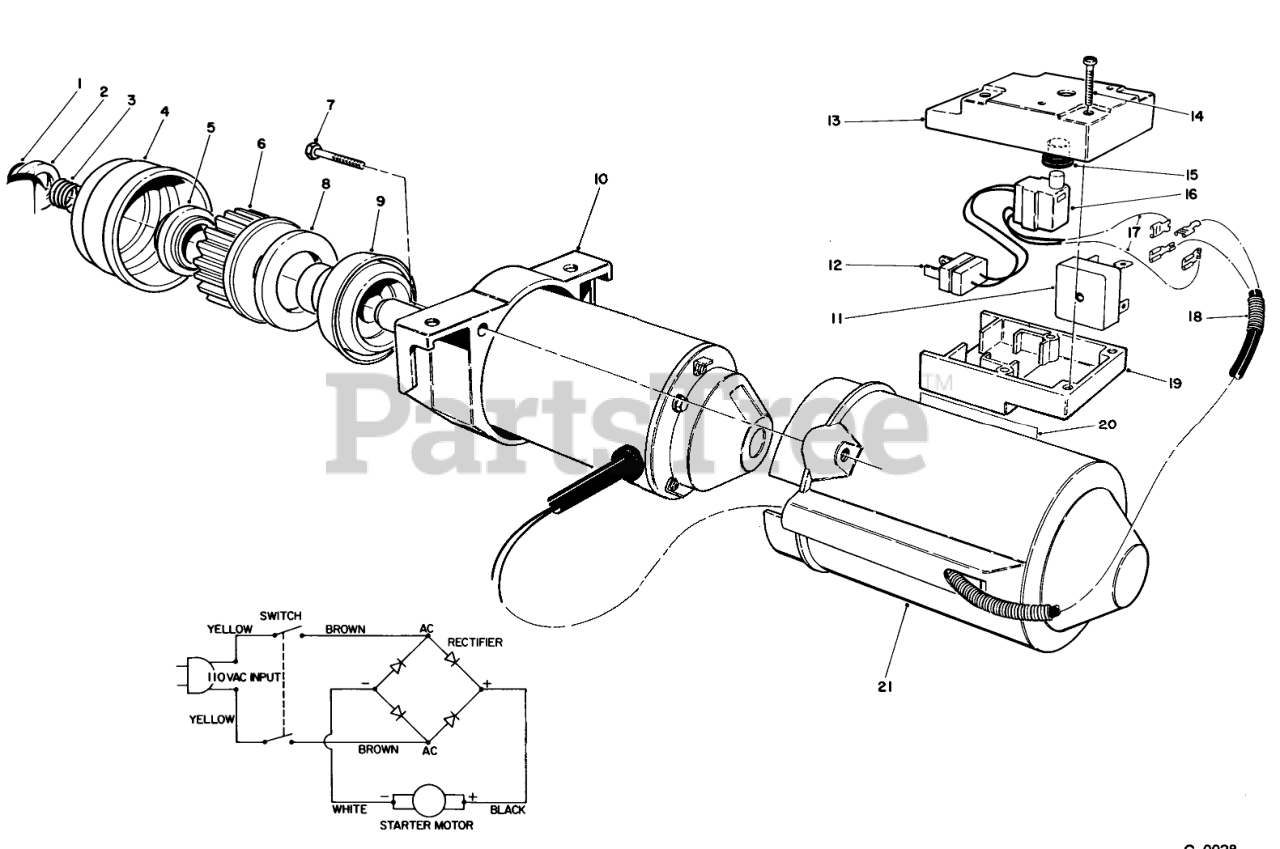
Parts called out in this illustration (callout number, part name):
1	RING-LOCK
2	PINION STOP
3	Spring
4	Retainer
6	Gear-Pinion
7	Screw-Plastite
8	Ring-Rubber
9	Drive-Pinion
10	Starter Motor Assembly (Incl. Ref. #1-6, 8 & 9)
11	RECTIFIER-BRIDGE
12	Plug
13	SWITCH BOX CAP
14	Screw-Plastite
15	BOOT-SWITCH
16	SWITCH-STARTER
18	CABLE COVER
19	SWITCH BOX BASE
20	Decal-UL
21	STARTER MOTOR COVER
